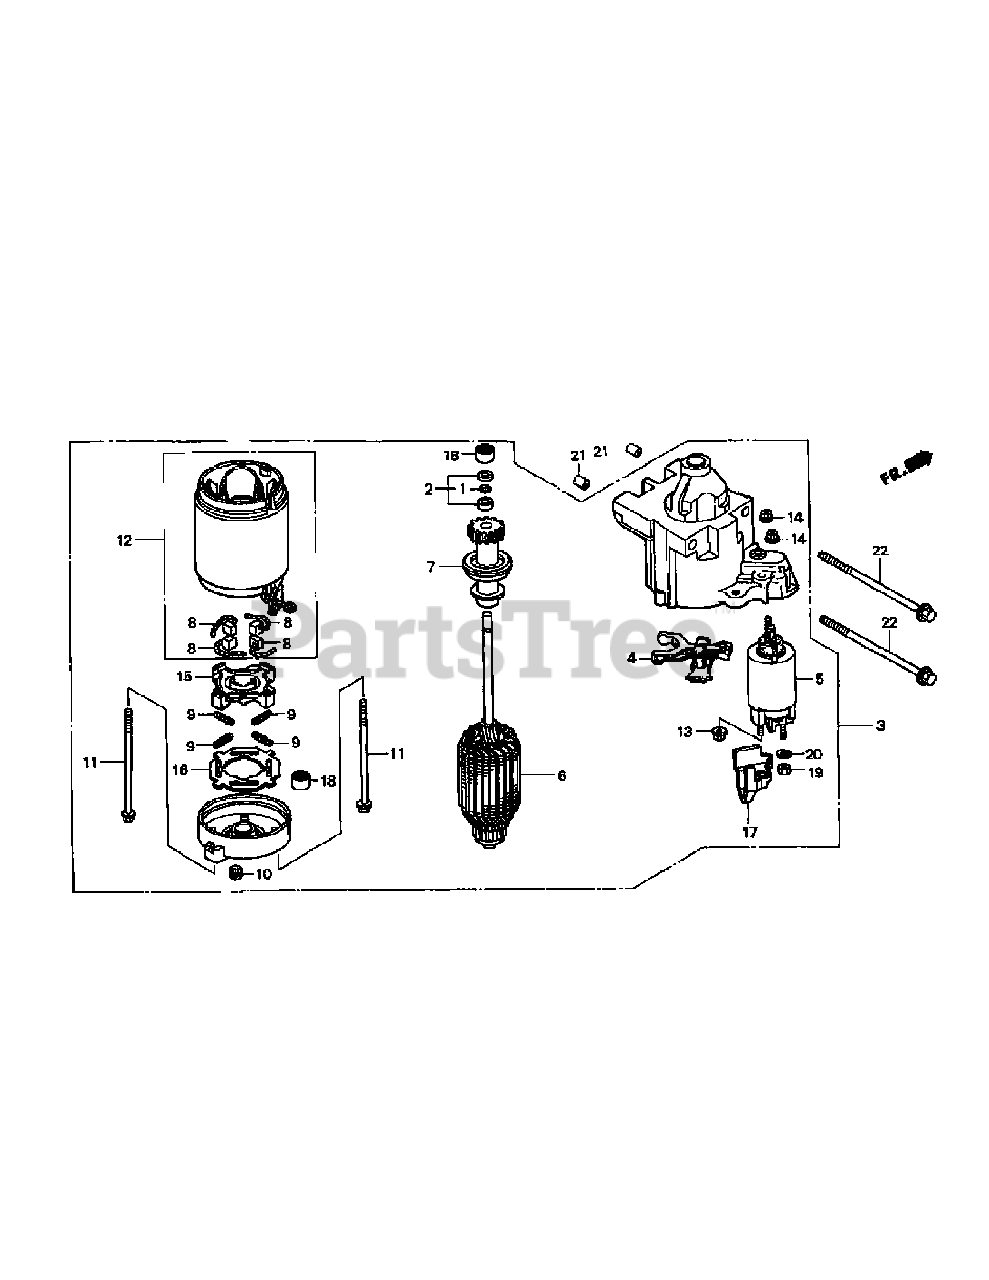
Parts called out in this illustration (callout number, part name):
2	Clutch Stop Collar Set
3	Starter Motor Assy.
4	Pinion Drive Lever
5	Magnet Switch Assy.
7	Overrunning Clutch
9	Brush Spring
11	Through Bolt
13	Hex Nut (8mm)
14	Flange Nut (5mm)
15	Brush Holder
16	Brush Holder Insulator
17	Terminal Cover
19	Hex Nut (8mm)
20	Spring Washer (8mm)
21	Dowel Pin
22	Flange Bolt (8x110)
